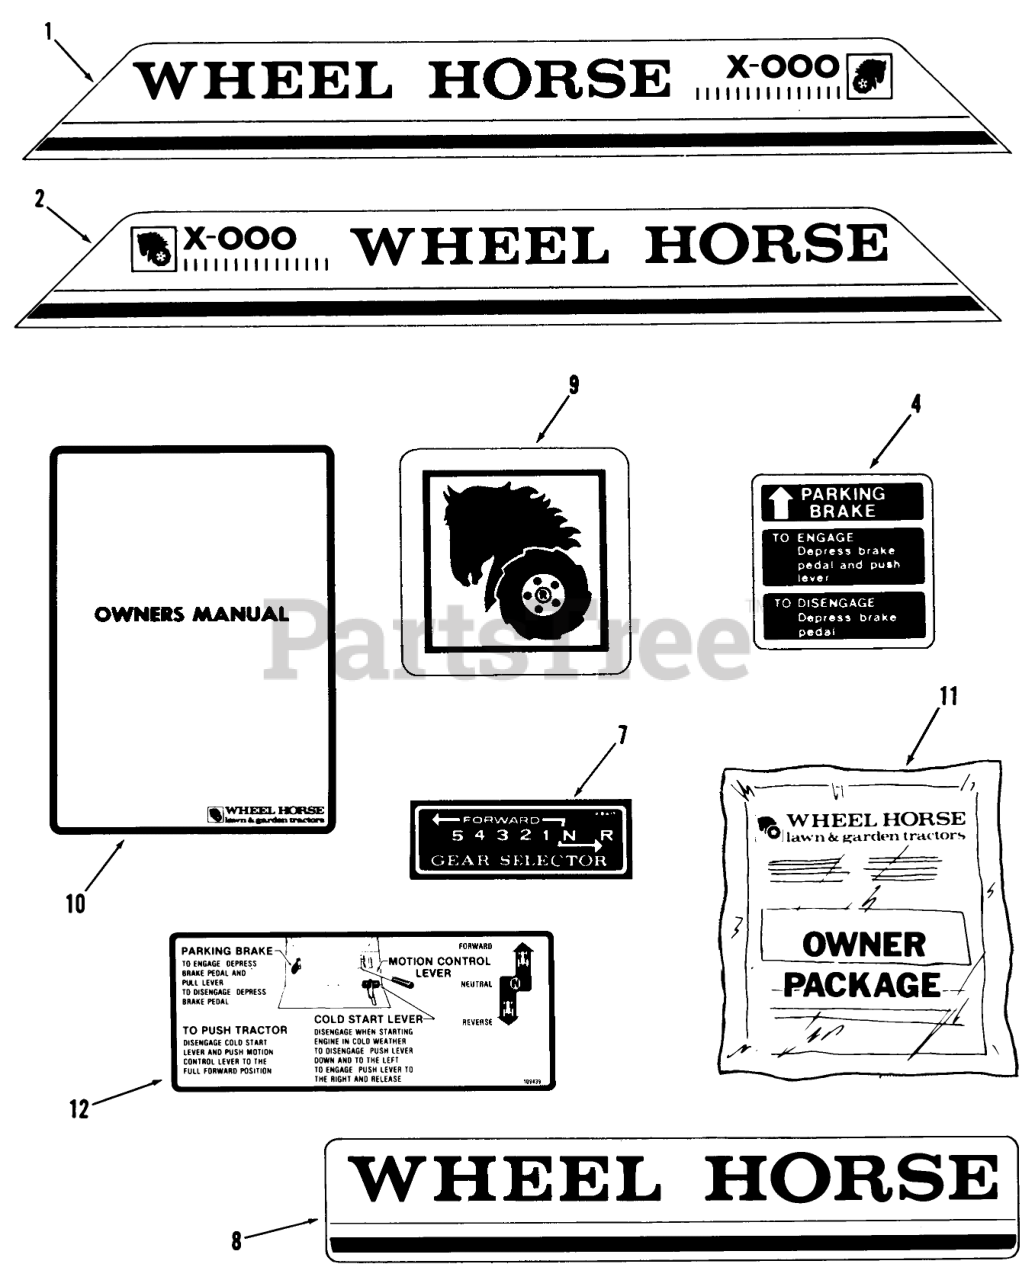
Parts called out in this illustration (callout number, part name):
1	HOOD-DECAL RH
1	Decal-Hood RH B-115
2	HOOD-DECAL LH
2	DECAL-HOOD B115 LH
4	Decal Parking Brake
7	DECAL-SHIFT
8	DECAL-REAR
9	DECAL-LOGO
10	Owner-s Manual-Tractor
11	New Tractor Loose Parts Package B-165 Automatic Only
11	New Tractor Loose Parts Package B-115 5-Speed Only
12	DECAL-SPD CONTROL
